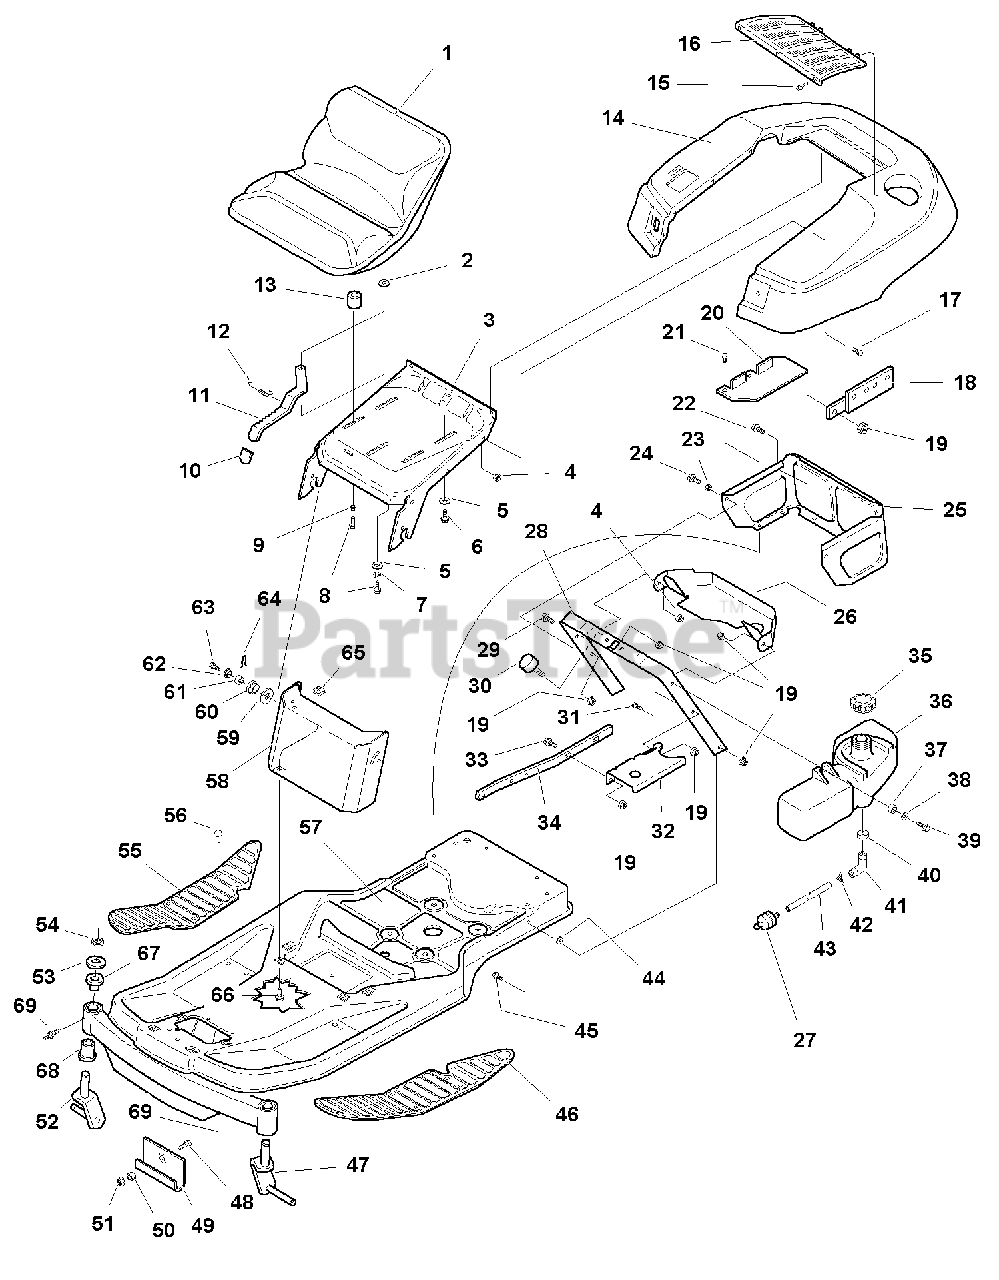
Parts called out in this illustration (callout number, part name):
1	SEAT, High Back, Replacement (**See Footnote)
3	SUPPORT, Seat
4	NUT, Hex Flange Lock, 1/4-20
5	WASHER, Plain
6	CAPSCREW, Hex Lock, 5/16-18 x 3/4
7	LOCKWASHER, 5/16
8	CAPSCREW, Hex, 5/16-18 x 1-1/4
9	NUT, Hex, 5/16-18
11	ADJUSTER, Seat
13	SPACER, Seat Slide
14	DECK, Seat (Orange)
14	DECK, Seat (Red)
16	SCREEN
17	CAPSCREW, Hex Flange Lock, 1/4-20 x 5/8
18	SUPPORT, Reservoirs
19	NUT, Hex Flange Lock, 5/16-18
20	PLATE, Battery
21	CAPSCREW, Taptite, 1/4-20 x 1/2
22	CAPSCREW, Hex Head, 5/16-18 x 5/8
24	CAPSCREW, Hex Head, 5/16-18 x 1-3/4
25	SHROUD, Rear
26	DUCT, Air Inlet
27	FILTER, Fuel
28	SUPPORT, Seat Deck
29	CAPSCREW, Hex Head, 1/4-20 x 3/4
31	CAPSCREW, Hex Head, 5/16-18 x 1
32	SUPPORT, Fuel Tank
33	CARRIAGE BOLT, 5/16-18 x 1
34	STRAP, Fuel Tank, Brace
35	CAP, Fuel Tank
38	WASHER
39	CAPSCREW, Taptite Washer Head, 5/16-18 x 1-1/4
40	BUSHING, Rubber
41	FITTING, Elbow
42	CLAMP, Hose
44	NUT, Push Pal, 5/16
45	CAPSCREW, Hex Flange Whiz Lock, 5/16-18 x 3/4
46	FOOTREST PAD, LH
47	SPINDLE ASSEMBLY, LH
48	CAPSCREW, Hex Head, 1/2-13 x 1-1/2
49	HOOK, Mower
51	NUT, Flange Lock, 1/2-13
52	SPINDLE ASSEMBLY, RH
53	WASHER
54	E-RING Retainer
55	FOOTREST PAD, RH
56	FASTENER, Panel
57	FRAME ASSEMBLY
58	PANEL, Front
59	WASHER, Plain
60	SPACER, Hood, Plastic
62	PIVOT, Hood
63	CAPSCREW, Taptite, 5/16-18 x 1
65	NUT, Pal, 5/16-18
66	CAPSCREW, Hex Flange Whiz Lock, 5/16-18 x 3/4
67	BUSHING, Upper
68	BEARING, Lower
69	FITTING, Grease
